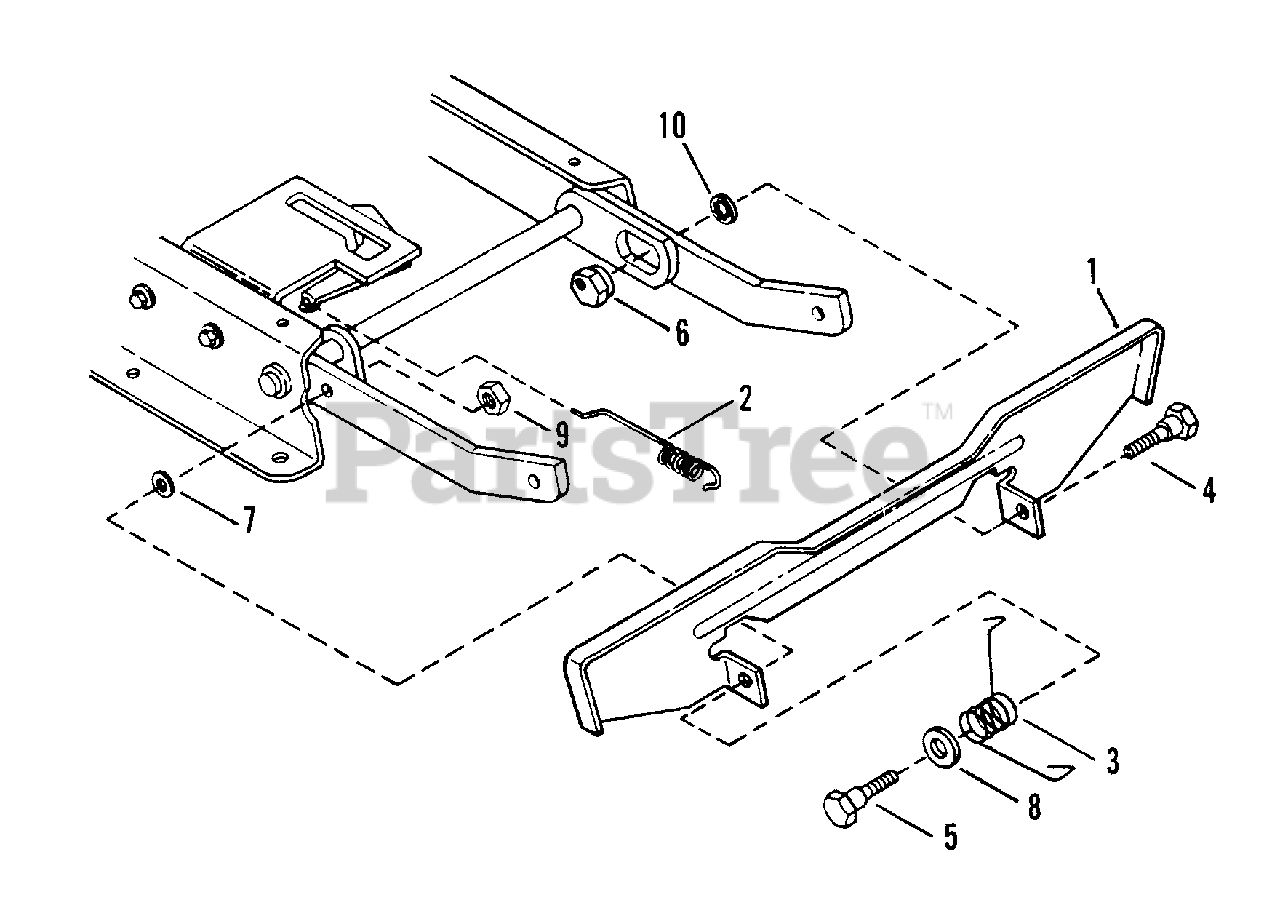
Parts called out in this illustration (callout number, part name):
1	PEDAL, Blade Stop Control
2	SPRING, Latching
3	SPRING, Pedal
4	BOLT, 3/8-24 x 3/4" Shoulder
5	BOLT, 3/8-24 x 9/16" Shoulder
6	ECCENTRIC, Leveling
7	WASHER, 3/8" Flat
8	WASHER, 1/2 Flat
9	NUT, 3/8-24 Hex Lock
10	WASHER, 3/8 Internal Tooth Lock
